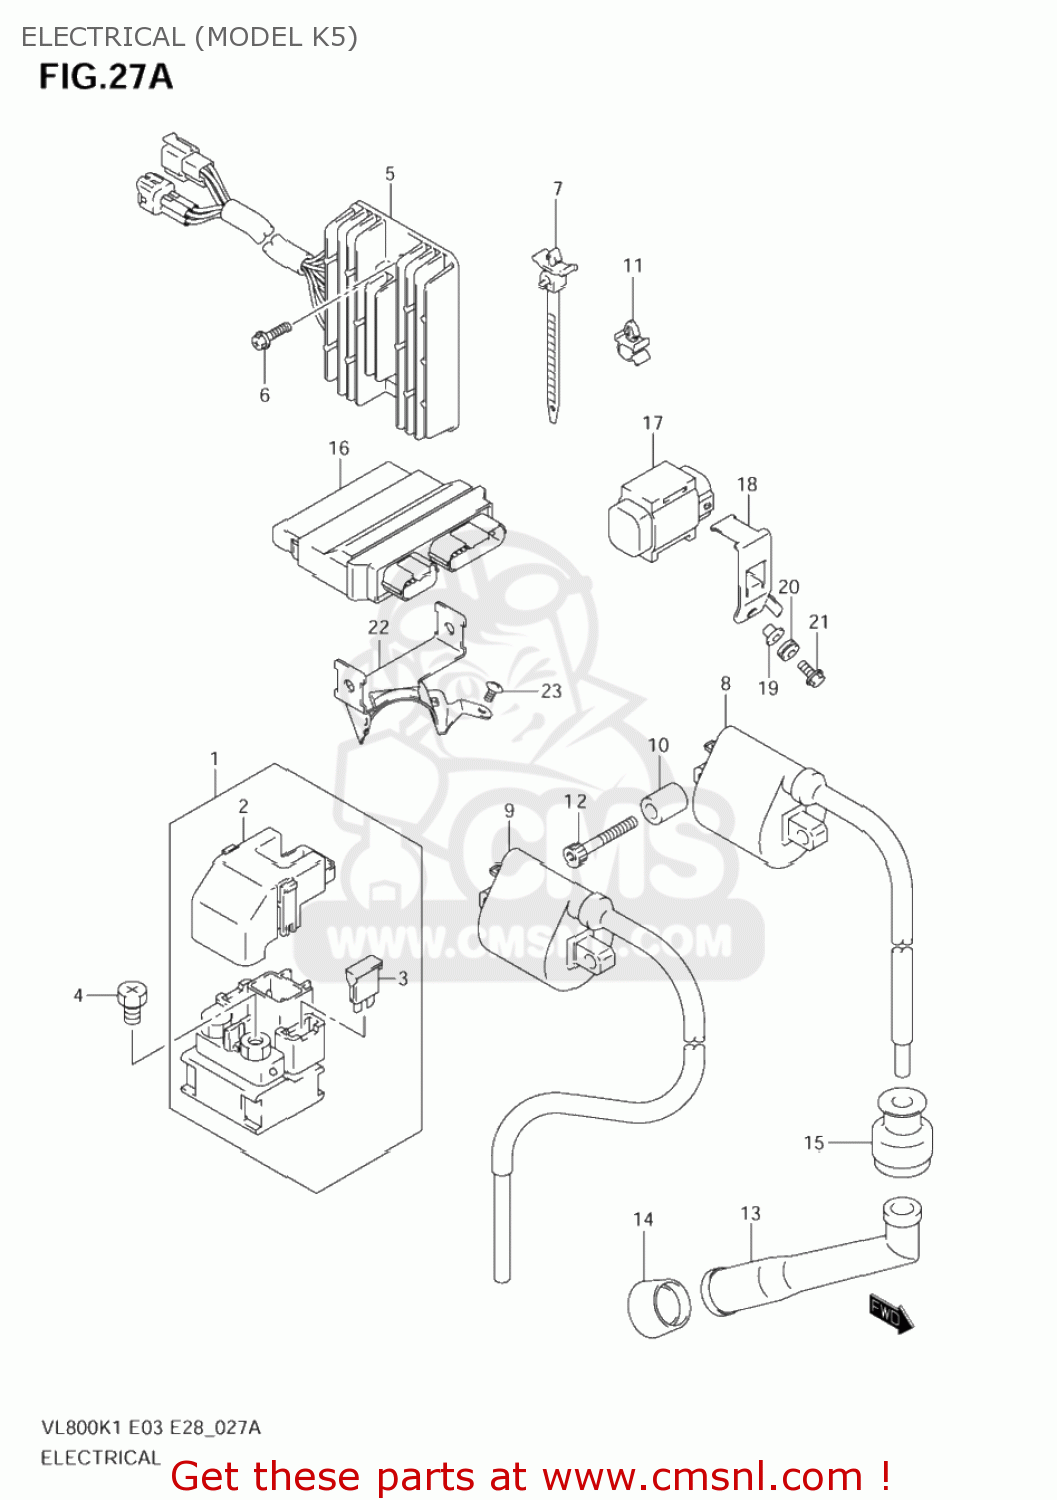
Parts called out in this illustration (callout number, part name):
1	RELAY ASSY,STARTING MOTOR
2	COVER
3	FUSE(30A)
4	SCREW(6X8)
5	RECTIFIER ASSY
6	BOLT
7	CLAMP(L:90)
8	COIL ASSY,IGNITION
9	COIL ASSY,IGNITION
10	SPACER(6.4X10X18)
11	CLAMP
12	BOLT
13	CAP,SPARK PLUG
14	SEAL,SPARK PLUG
15	SEAL,HIGH TENSION CORD
16	CONTROL UNIT,FI
17	SENSOR ASSY,FUEL CUT
18	BRACKET,FUEL CUT SENSOR
19	SPACER(6.2X8.4X6.9)
20	CUSHION
21	BOLT
22	BRACKET,FI CONTROL UNIT
23	SCREW(6X12)
